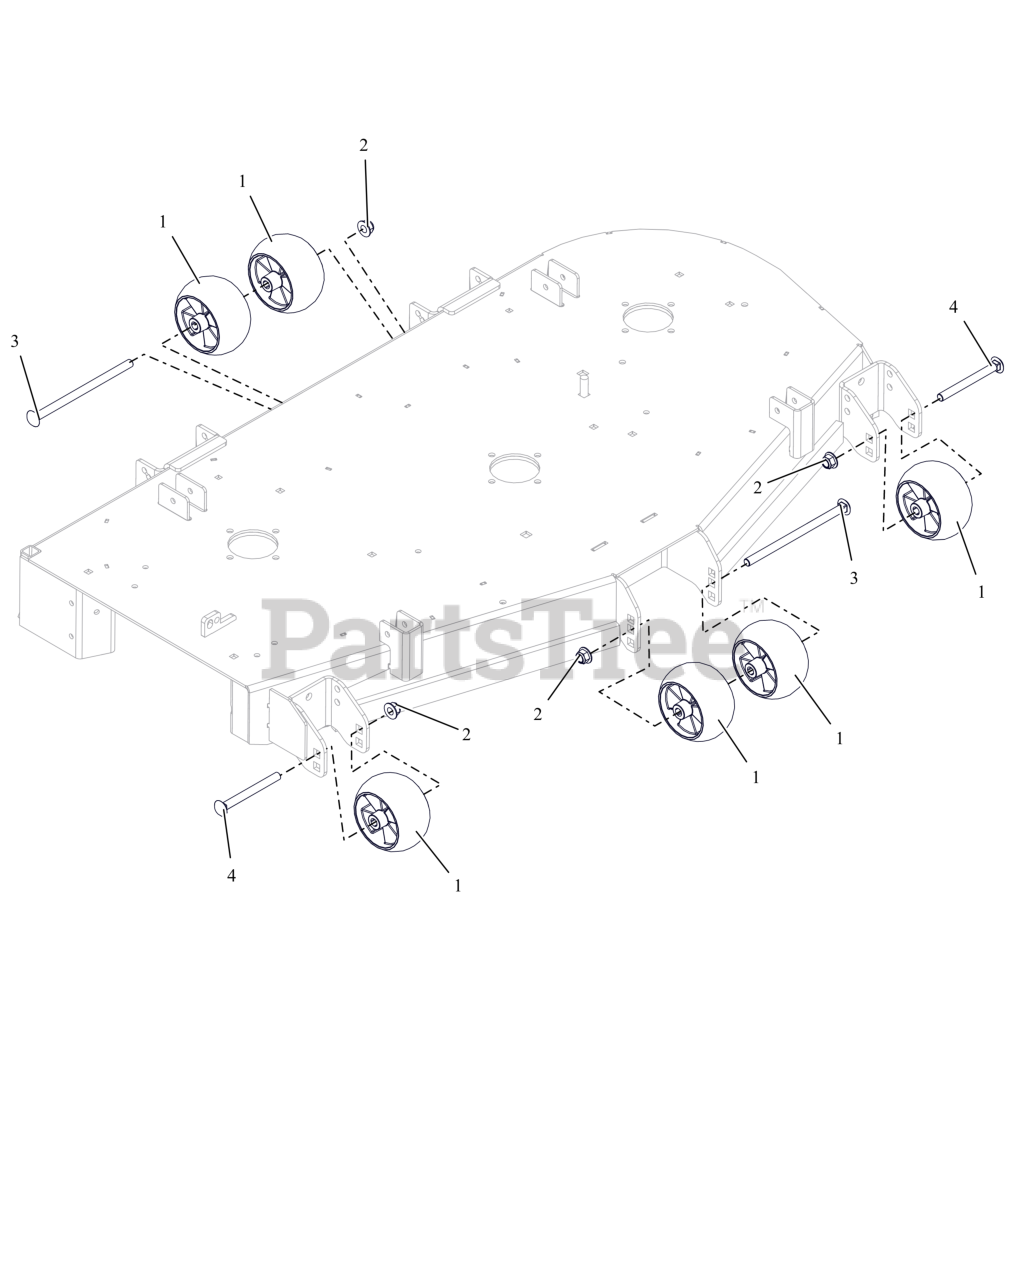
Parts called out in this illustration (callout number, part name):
1	WHEEL, ANTI SCALP - 5X3 CTR W/RIBS
2	NUT,NYL-FLG .50-13 GF ZCC
3	BTL,RHSN .500-13 X 8.5S G5 ZCC
4	BLT, RHSN .50-13X5.00 G5 ZCC
